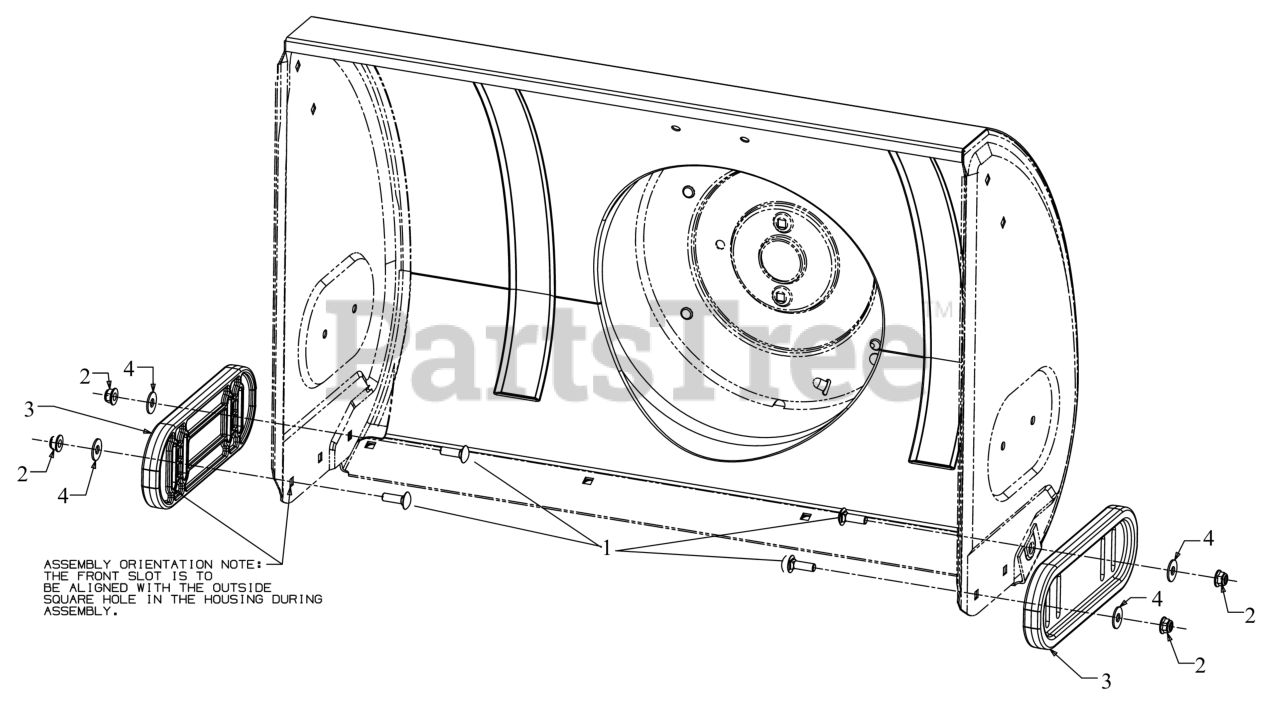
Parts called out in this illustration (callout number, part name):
1	CARRIAGE BOLT 5/16-18 x 1.00
2	FLANGE LOCK NUT 5/16-18
3	DELUXE SLIDE SHOE
4	FLAT WASHER
